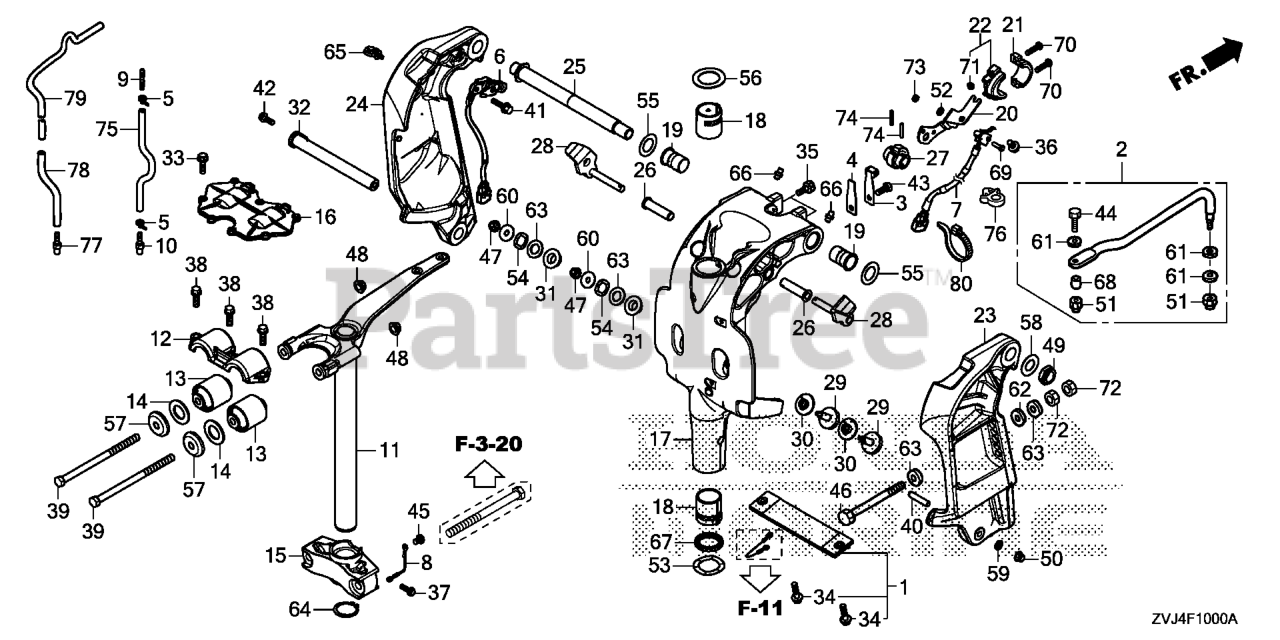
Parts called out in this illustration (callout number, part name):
1	METAL KIT, ANODE Use from Frame SN 4800343.
2	ROD KIT, STEERING
3	SPRING, CLICK
4	SPRING, CLICK ASSIST
5	BAND, WIRE
6	SENSOR ASSY., TRIM ANGLE
7	SWITCH ASSY., TILT LIMIT
8	WIRE, LEAD (1.5X116MM)
9	END, NIPPLE
10	NIPPLE, SENSOR
11	FRAME, MOUNTING (XL)
11	FRAME, MOUNT XL
12	HOUSING, MOUNTING (UPPER)
13	MOUNT, RUBBER (UPPER)
14	RUBBER, MOUNT STOPPER (UPPER)
15	HOUSING, CENTER MOUNTING (LOWER) (XL)
16	COVER, MOUNT (UPPER)
17	CASE, SWIVEL *NH565* (XL) (GRAND PRIX WHITE)
17	CASE, SWIVEL *NHB14M* (XL) (AQUA MARINE SILVER METALLIC)
18	LINER, SWIVEL CASE
19	BUSH, SWIVEL CASE
20	BRACKET, TILT LIMIT SWITCH
21	CAM A, TILT LIMIT ANGLE
22	CAM B, TILT LIMIT ANGLE
23	BRACKET, R. STERN *NHB14M* (AQUA MARINE SILVER METALLIC)
23	BRACKET, R. STERN *NH565* (GRAND PRIX WHITE)
24	BRACKET, L. STERN *NH565* (GRAND PRIX WHITE)
24	BRACKET, L. STERN *NHB14M* (AQUA MARINE SILVER METALLIC)
25	SHAFT, TILTING
26	BUSH, TILT ARM
27	BRACKET, TILTING
28	STOPPER, TILT
29	RECEIVER, THRUST
30	BUSH A, THRUST RECEIVE
31	BUSH B, THRUST RECEIVE
32	SHAFT, CYLINDER (LOWER)
33	BOLT, FLANGE (6X20) (ENGINE NO.)
34	BOLT, FLANGE (6X23) Use from Frame SN 4800343.
35	BOLT (1/4-28UNF)
36	BOLT, FLANGE (6X12) Use from Frame SN 1005249.
37	BOLT, FLANGE (6X12)
38	BOLT-WASHER (10X32)
39	BOLT, HEX. (12X200)
40	BOLT, STUD (10X28)
41	BOLT, FLANGE (6X20) (ENGINE NO.)
42	BOLT, FLANGE (8X22)
43	BOLT, HEX. (6X14)
44	BOLT (3/8-24UNF)
45	SCREW, PAN (6X8)
46	BOLT, HEX. (12X130)
47	NUT, SELF-LOCK (6MM)
48	NUT, FLANGE (12MM)
49	NUT, SELF-LOCK (7/8-14UNF)
50	NUT, FLANGE (10MM)
51	NUT, SELF-LOCK (3/8-24UNF)
52	WASHER, PLAIN (4MM) Use from Frame SN 4800713.
53	WASHER, WAVE (40MM)
54	WASHER, WAVE (12MM)
55	WASHER, WAVE (26MM)
56	WASHER, THRUST (34MM)
57	WASHER, MOUNTING STOPPER (UPPER)
58	WASHER (7/8")
59	WASHER, PLAIN (10MM)
60	WASHER, PLAIN (6MM)
61	WASHER (10MM)
62	WASHER, PLAIN (12MM)
63	WASHER, PLAIN (12MM)
64	CIRCLIP (OUTER) (39MM)
65	CLIP, WIRE HARNESS
66	NIPPLE, GREASE
67	OIL SEAL (39.5X52X6) (ARAI)
68	COLLAR, STEERING ROD
69	SCREW, PAN (4X14)
70	SCREW, PAN (5X20)
71	NUT, HEX. (5MM)
72	NUT, HEX. (12MM)
73	NUT, HEX. (4MM)
74	PIN, SPRING (3X20)
75	BULK HOSE, VACUUM (5X3000) (5X250)
76	CLIP, TUBE
77	NIPPLE, SENSOR
79	BULK HOSE, VACUUM (5X3000) (5X250)
80	BAND (BLACK 3.5X140)
